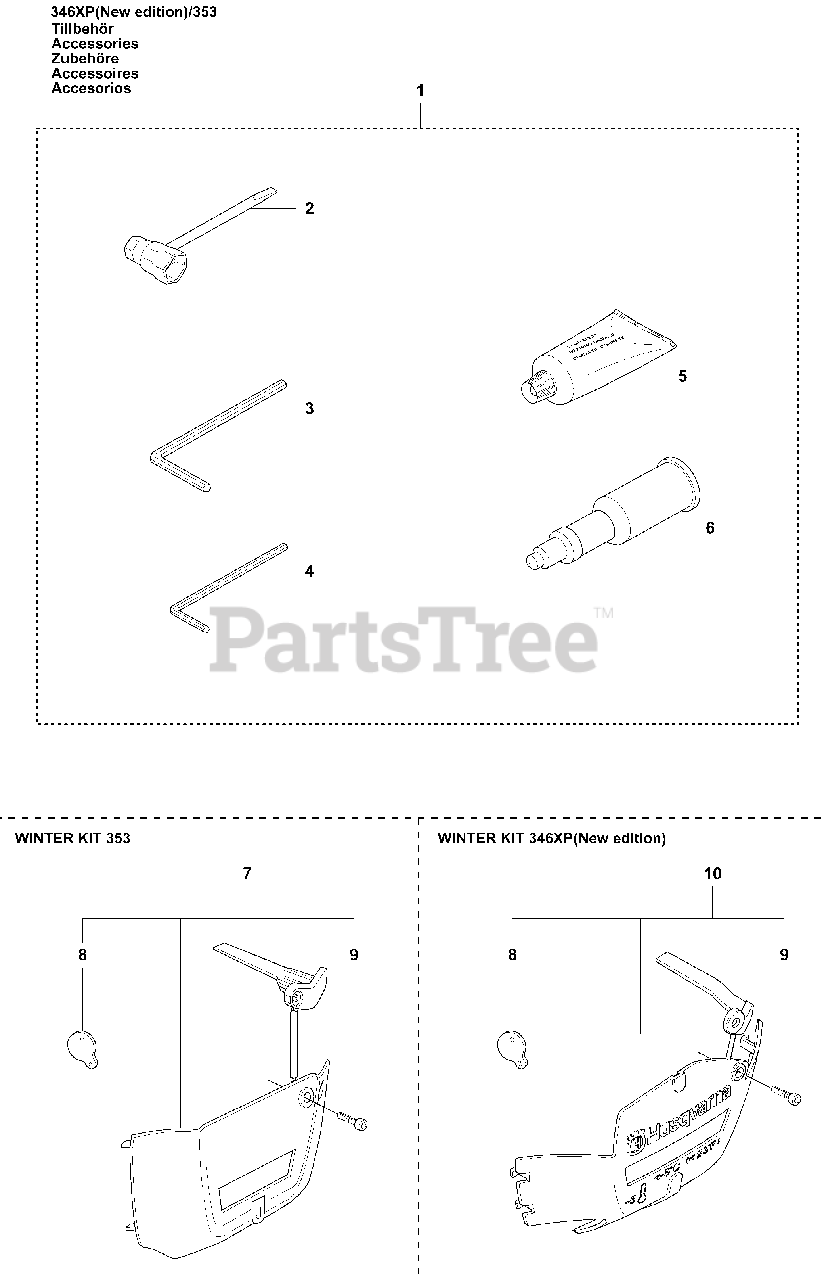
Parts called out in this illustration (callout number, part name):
1	SCRENCH
2	COMBI TOOL
5	GREASE
6	Grease Gun
7	WINTER COVER
8	COVER
10	WINTER COVER
